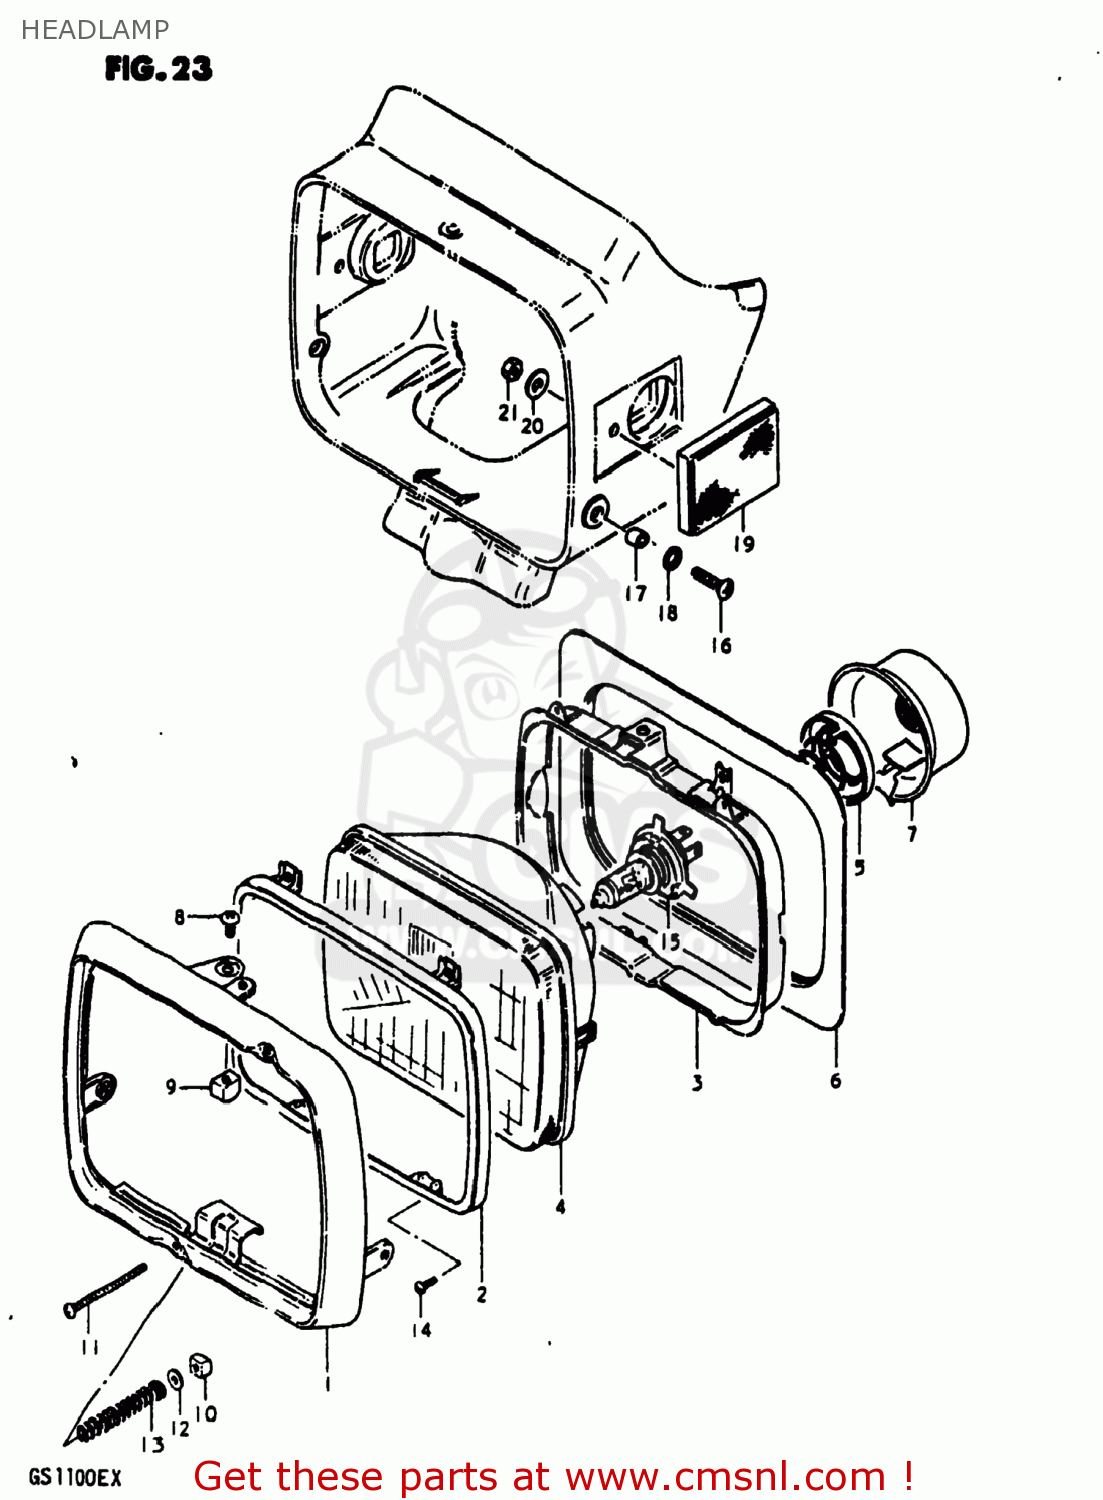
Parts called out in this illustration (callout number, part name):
1	RIM
2	RETAINER,HEADLAMP
3	RING,HEADLAMP UNIT
4	LAMP UNIT
5	HOLDER
6	SHADE
7	COVER,HEADLAMP SOCKET
8	SCREW
9	NUT,HEADLAMP ADJUSTER
10	NUT
11	SCREW,HEADLAMP ADJUST
12	WASHER
13	SPRING
14	SCREW
15	BULB(12V60/55W,H4)
16	SCREW
17	SPACER (5.2X8X7.5)
18	GASKET(8.2X12X0.8) (NAS)
19	REFLEX REFLECTOR,FR
20	WASHER(5.2X16X1)
21	NUT
